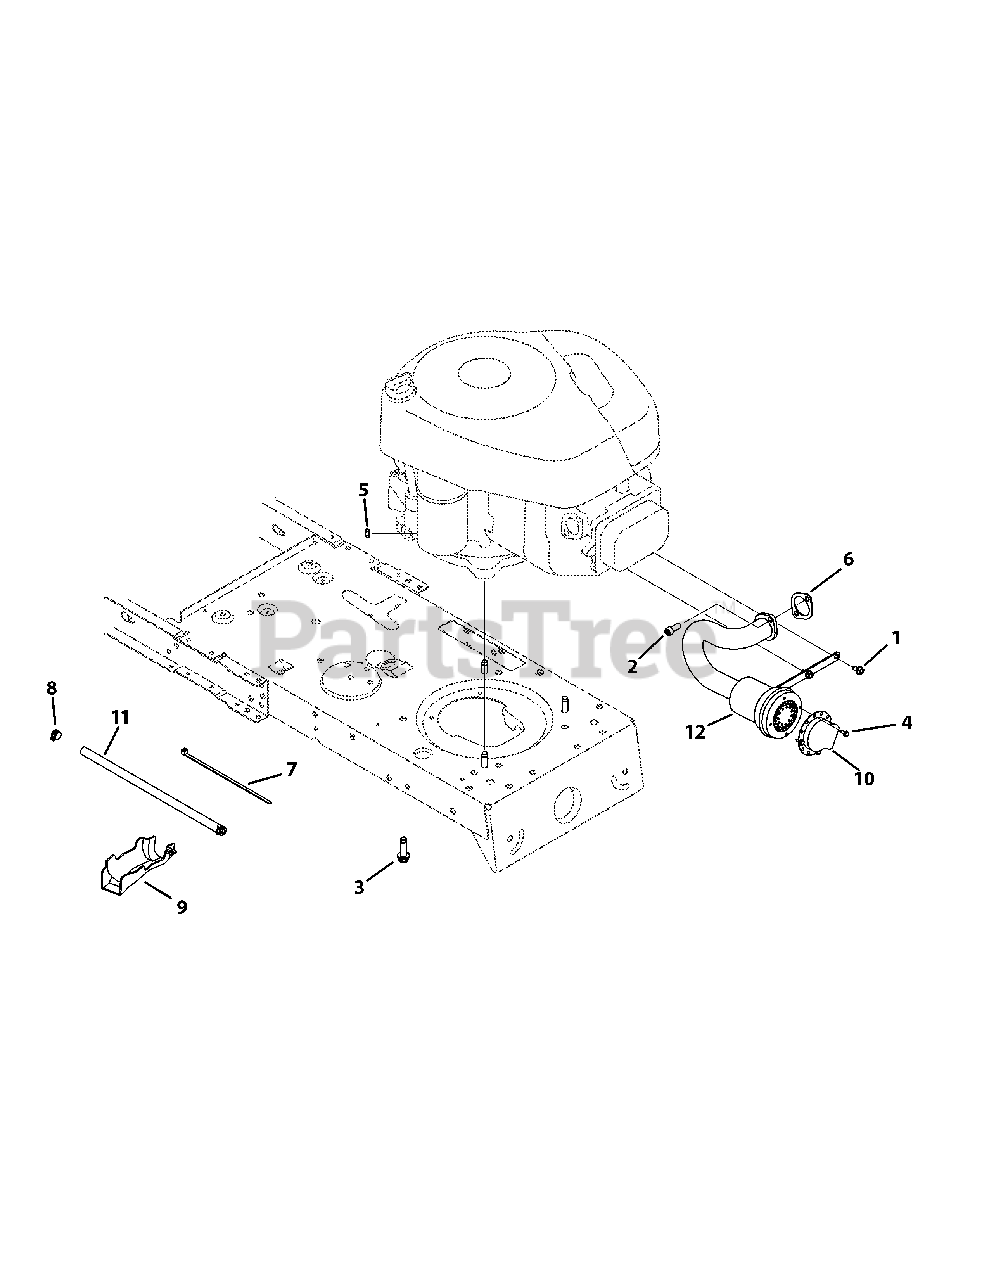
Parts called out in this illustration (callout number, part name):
1	Hex Wash S-Tapp Scr 1/4-20 x .50
2	Socket HD Cap Scr. 5/16-18 x .75
3	Hex Wash S-Tapp Scr 3/8-16 x 1.0
4	Hex Wash HD AB S-Tapp Scr #8-.50
5	Sems Nut 1/4-20
6	Exhaust Gasket
7	Cable Tie
8	Hose Clamp
9	Oil Drain Sleeve
10	Muffler Deflector
11	Fuel Line
12	Muffler, Bug
